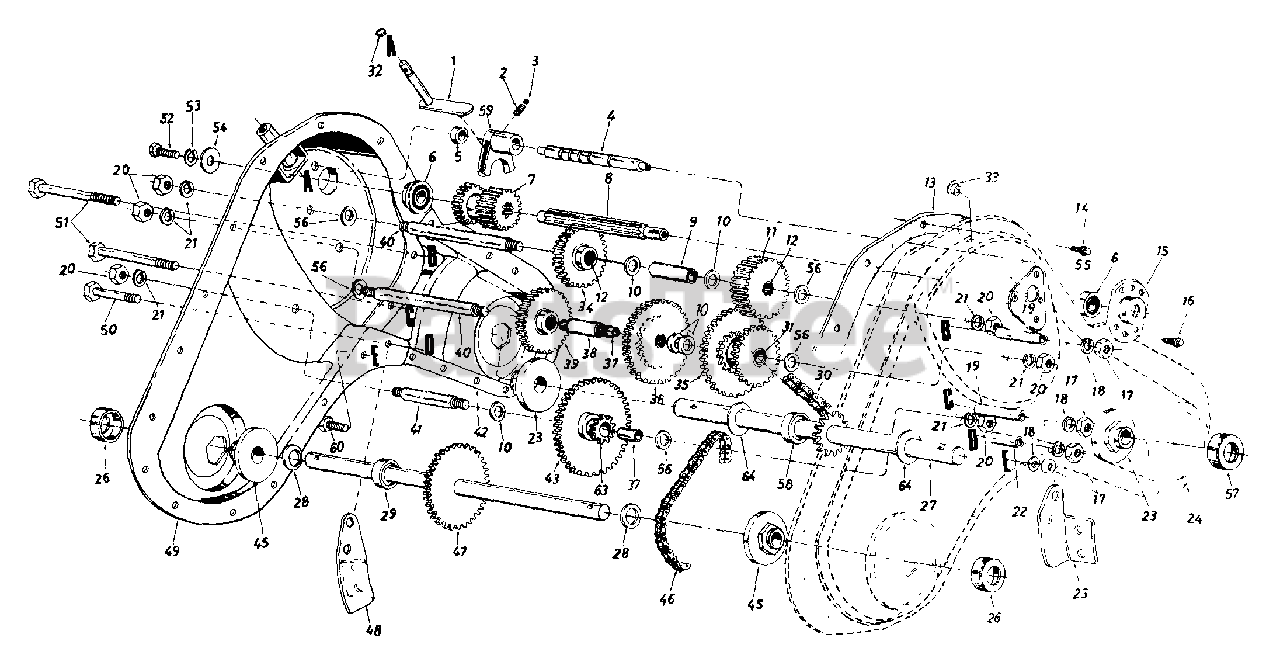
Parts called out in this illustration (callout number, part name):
1	Shifting Bracket Ass'y.
2	Compression Spring .50" Lg.
3	Ball Detent .250" Dia.
4	Detent Shaft 1/2" Dia.
5	Spacer .505" I.D. x .88" O.D.
6	Ball Brg..62" I.D. x 1.38"
7	Spur Gear 16T (Input)
8	Input Spline Shaft 7/8"
9	Spacer .657" I.D. x 2.85" Lg.
10	FI-Wash..640" I.D. x 1.24"
11	Spur Gear 30T 7/8" I.D.
12	Needle Bearing 5/8" I.D.
13	Gasket - Trans. Hsg.
14	Hex S-Tap Scr. 1/4-20 x .5"
15	1-3/8" Dia. Bearing Housing
16	Hex TT-Tap Scr. 1/4-20 x .75"
17	Hex Nut 5/16-18 Thd.
18	L-Wash. 5/16" I.D.
19	Spacer 1.56" Lg.
20	Hex Nut 7/16-20 Thd.
21	Bell-Wash..45" I.D. x 1.0"
22	Spacer 1.015" Lg.
23	Tine Shaft Brg. 1.002 x 2.50
24	Trans. Housing Ass'y.- L.H.
27	Tine Shaft Ass'y. 1" O.D.
28	FI-Wash. .76" I.D. x 1.5" O.D.
29	Spacer .75" I.D. x .50" Lg.
30	Chain #50 5/8 Pitch x 52 Links - Endless
31	Needle Bearing 5/8" I.D.
32	Snap Ring
33	Taper Cap Plug
34	Spur Gear 30T 12/16" I.D.
35	30/44T Gear Ass'y. Comp.
36	Spur Gear 44T
37	Sleeve Bearing
38	Gear Hub 3/4" I.D. x 3" Lg.
39	Spur Gear 30T 1.0" I.D. x 1/2" W
40	Jack Shaft 5/8" Dia. x 5"
41	Jack Shaft 5/8" Dia. x 2.38"
45	Wheel Brg. 752" x 2.5"
46	4420 Chain 1/2 Pitch x 50 Links - Endless
47	Wheel Shaft Ass'y. 15.6"
51	Hex Bolt 5/16-18 x 2.5"
52	Hex Bolt 1/4-20 x .62" Lg.
53	L-Wash. 3/8" I.D.
54	Fl-Wash. 1/4" I.D. x .93" O.D.
55	Gear Positioner Bracket
56	Fl-Wash. 7/16" I.D. x 1-3/8"
57	Dust Cover Ass'y 1" Shaft
58	Spacer 1" I.D. x 2" O.D.
59	Shifting Fork
60	Hex Bolt 5/16-18 x .75" Lg
63	10T Sprocket Ass'y.
64	Thrust Wash. 1.03" I.D. x 1.62" O.D.
